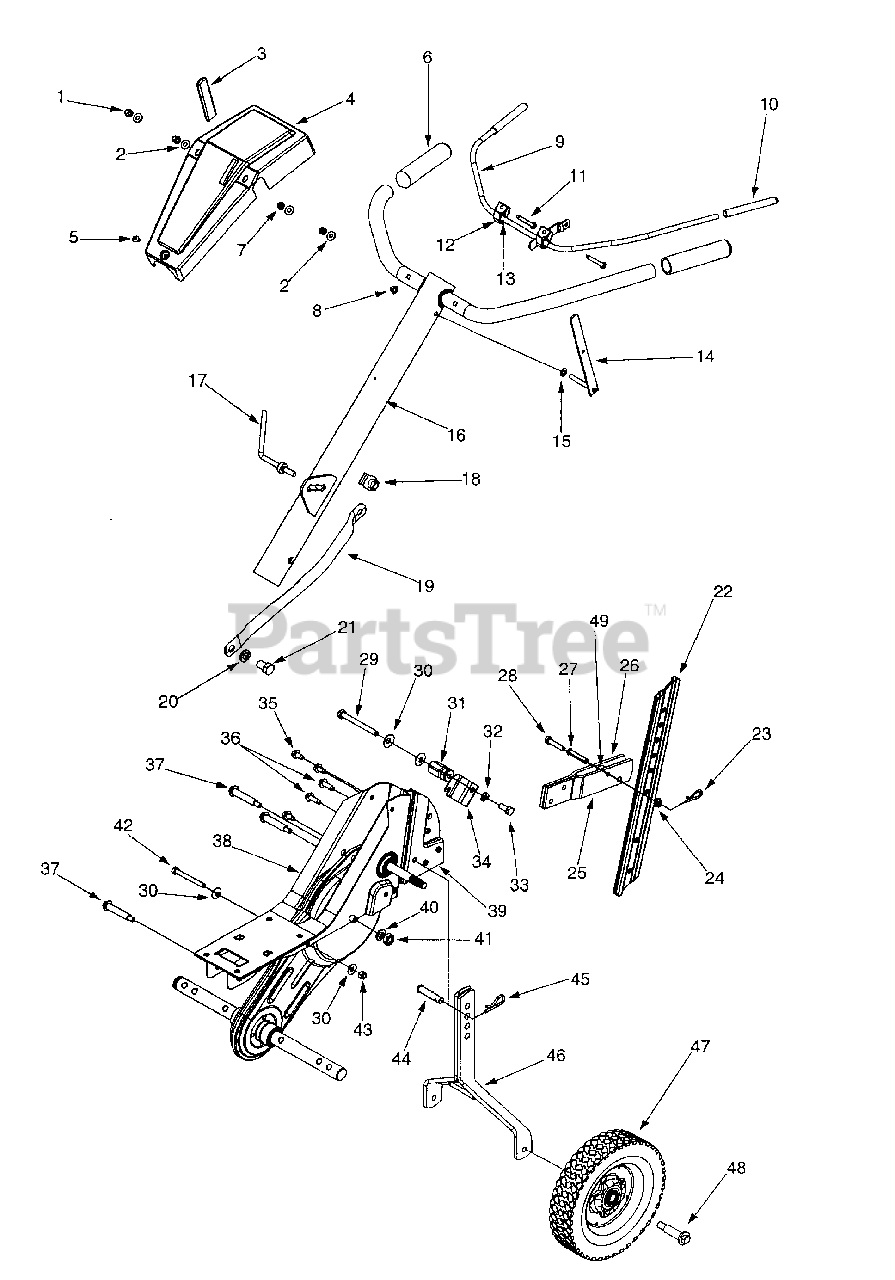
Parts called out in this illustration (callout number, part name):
1	Acorn Lock Nut 1/4-20
2	Flat Washer .271" I.D. x .630" O.D.
3	Reverse Handle Grip
4	Handle Cover
5	Truss Mach. Scr. #10 x 1/2" Lg.
6	Grip-Handle
7	Hex Nut 1/4-20 Gr.2
8	Cap Speed Nut
10	Grip-Clutch
11	Hex Bolt 1/4-20 x 2.25" Lg. Gr.5
12	Clutch Handle Holder
13	Flat Washer.385" I.D. x .62" O.D.
15	Flat Washer.344" I.D. x .62" O.D.
18	U Nut 5/16-18
21	Hex Bolt 1/2-20 Gr. 5
23	Cotter Pin
24	Hex Flange L-Nut 5/16-18
27	Clevis Pin
28	Hex Bolt 5/16-18 x 1.5" Lg.
29	Hex Bolt 5/16-18 x 3" Lg.
30	Wash. Bell. .340" I.D. x .872" O.D.
31	Spec. Hex Nut
32	L-Wash. 5/16" I.D.
33	Hex Bolt 5/16-18 Gr. 5
35	Hex Wash Screw 5/16-18 x .62"
36	Hex Wash. Hd. TT Tap Scr.
37	Shdl. Bolt 5/16-18
40	Lock Washer 7/16
41	Jam Nut 7/16-20 Gr. 2
42	Hex Bolt 5/16-18 x 2.75" Lg.
43	Hex Nut 5/16-18 Thd.
44	Clevis Pin
45	Cotter Pin
47	Wheel Ass'y 8" x 1.75"
48	Shoulder Screw .496 x 1.445
49	Spacer
